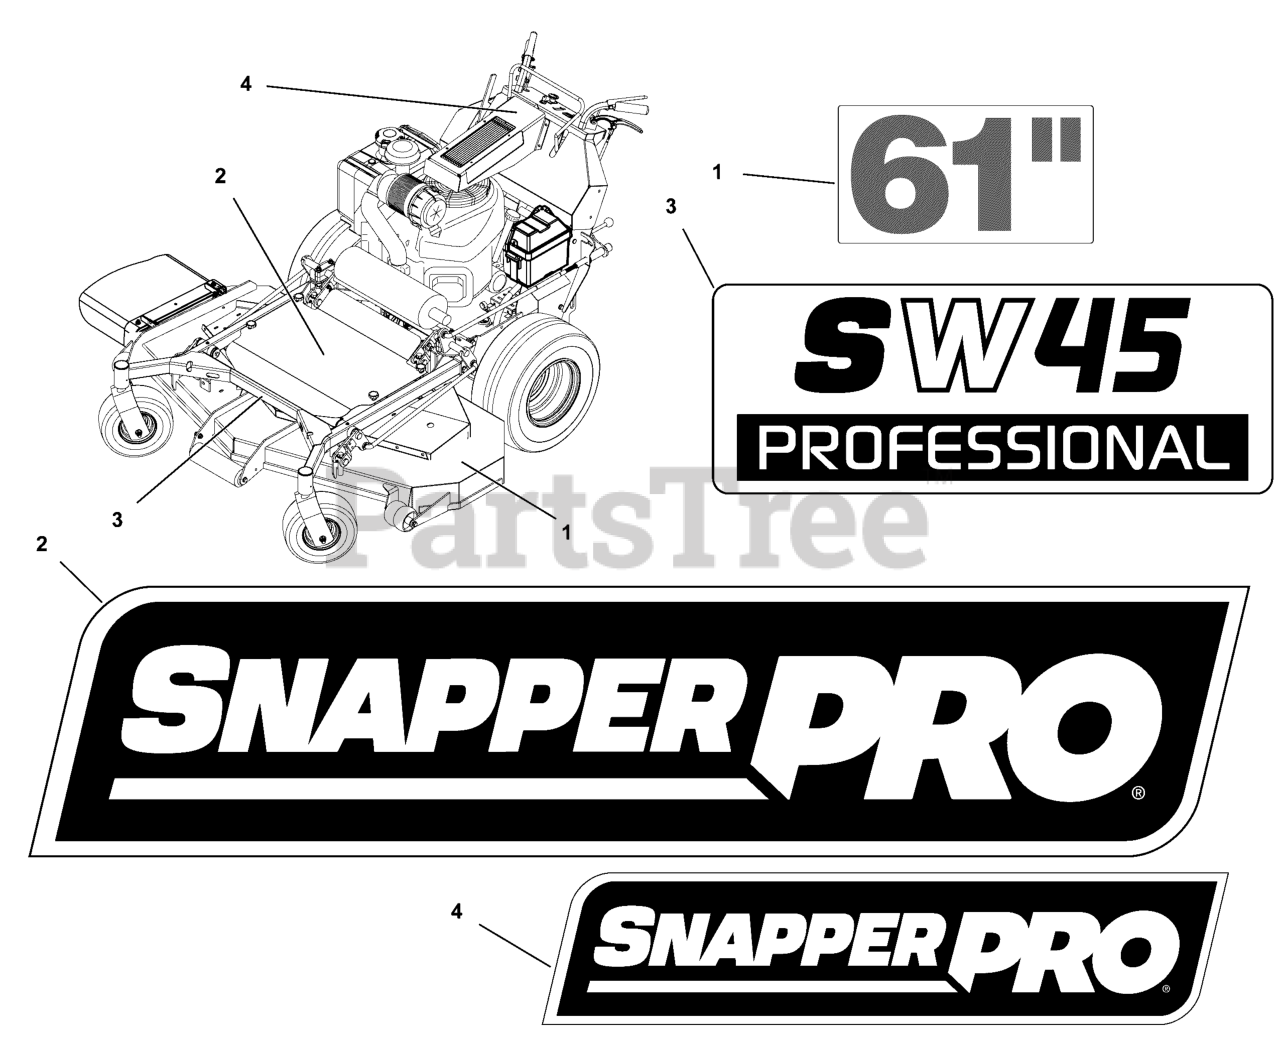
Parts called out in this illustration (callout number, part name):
1	DECAL, SNAPPER PRO LOGO, LARGE
2	DECAL, 61"
3	DECAL, MODEL, SW45
4	DECAL, SNAPPER PRO LOGO, X-SMALL
